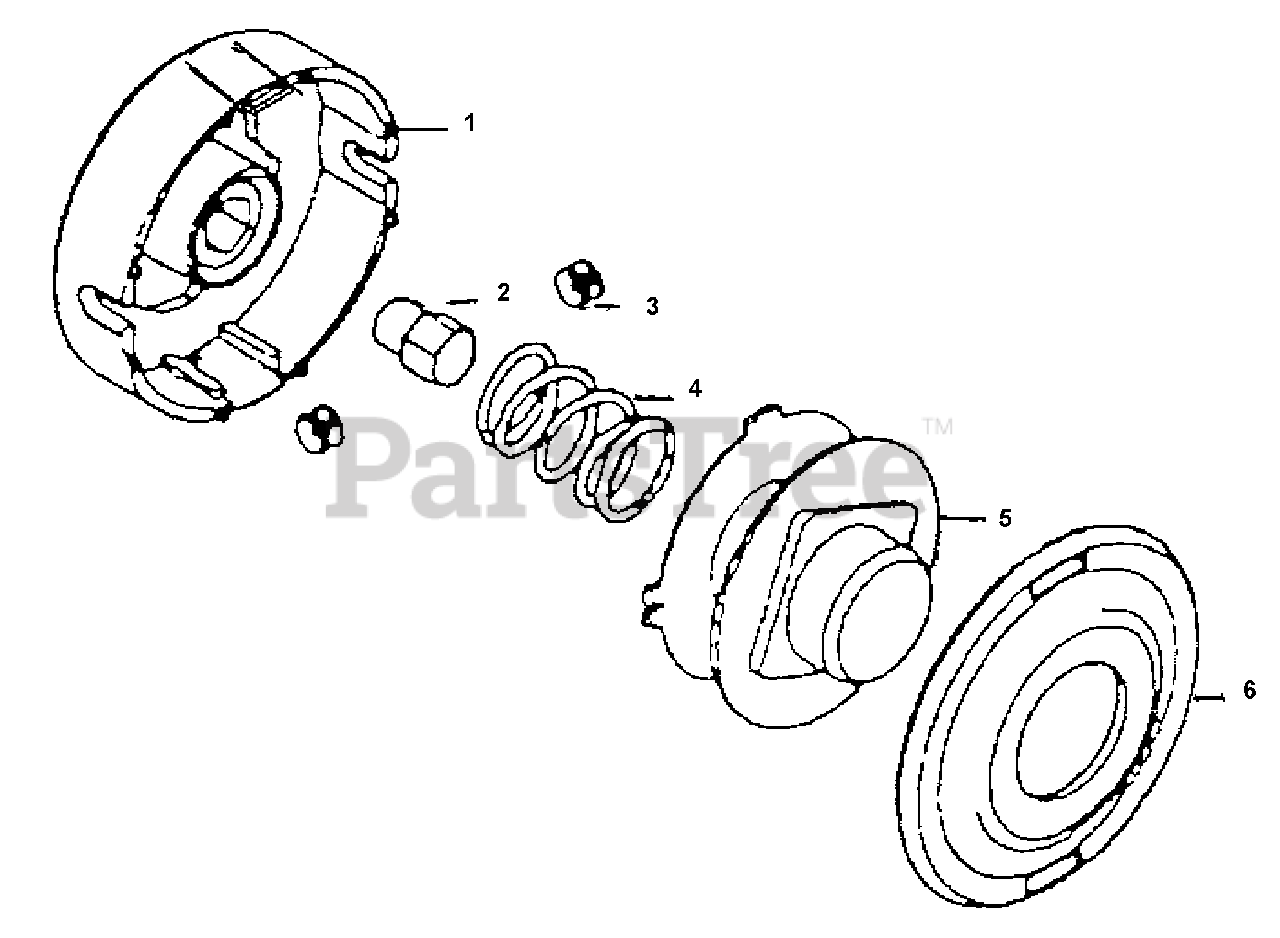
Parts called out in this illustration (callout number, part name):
1	HOUSING
2	NUT - LEFT HAND
3	EYELET
